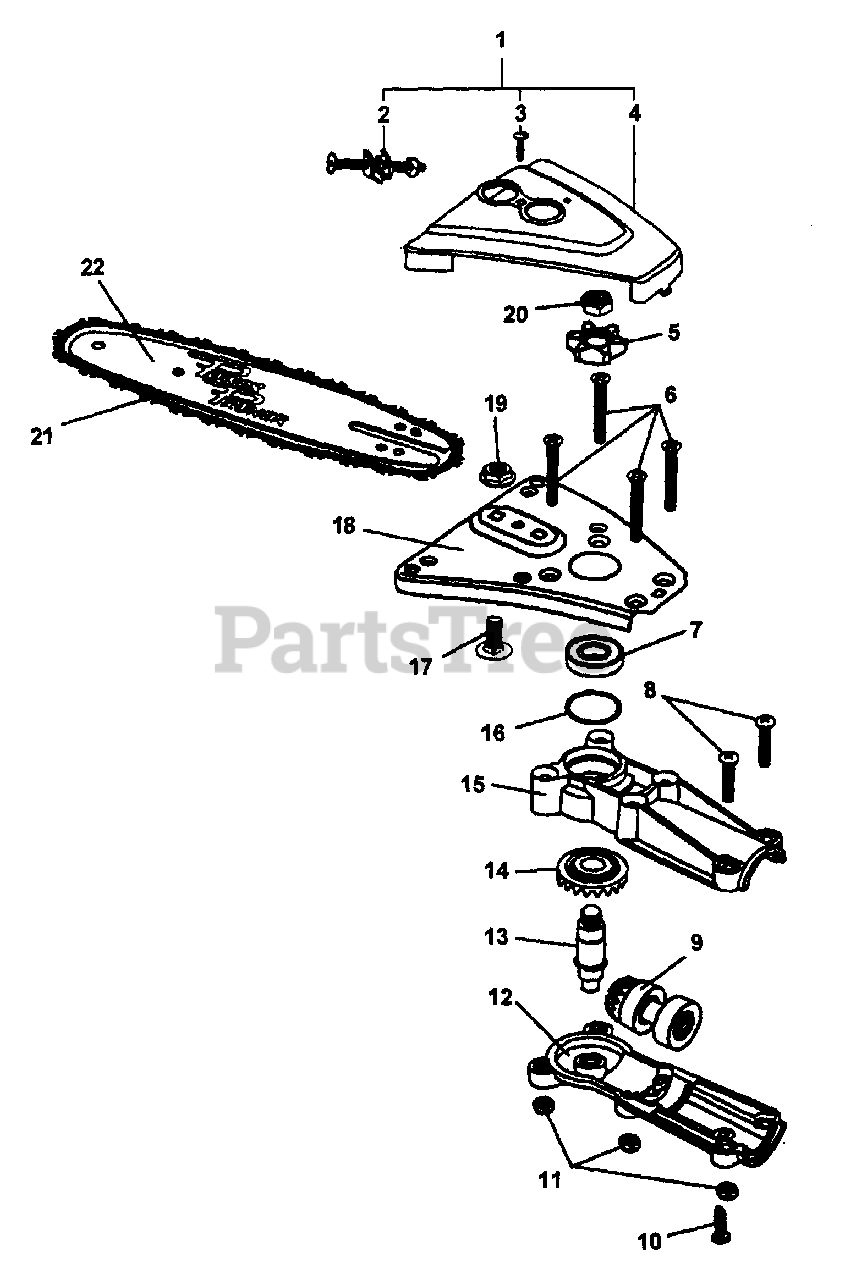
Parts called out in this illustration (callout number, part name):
1	SPROCKET COVER ASSY
2	TENSIONER KIT
3	SCREW - 8-32×1" - TORX PAN HEAD
4	GUARD, SPROCKET
5	SPROCKET
6	SCREW - TORX FLAT HEAD
7	BEARING, BALL 6001 DDU
8	SCREW, TORX 10-24 UNC 1-1/4
9	SHAFT, GEAR
10	SCREW - TORX PAN HEAD
11	NUT, LOCK 10-24 UNC
12	CASE, GEAR - RIGHT
13	SHAFT, GEAR
14	GEAR, BEVEL
15	CASE, GEAR - RIGHT
16	SHIM 0.004"
17	BOLT, CARRIAGE
18	SAW BAR CARRIER
19	NUT - FLANGE
20	NUT, HEX
21	SAWING CHAIN - 8"
22	GUIDE BAR - 8"
